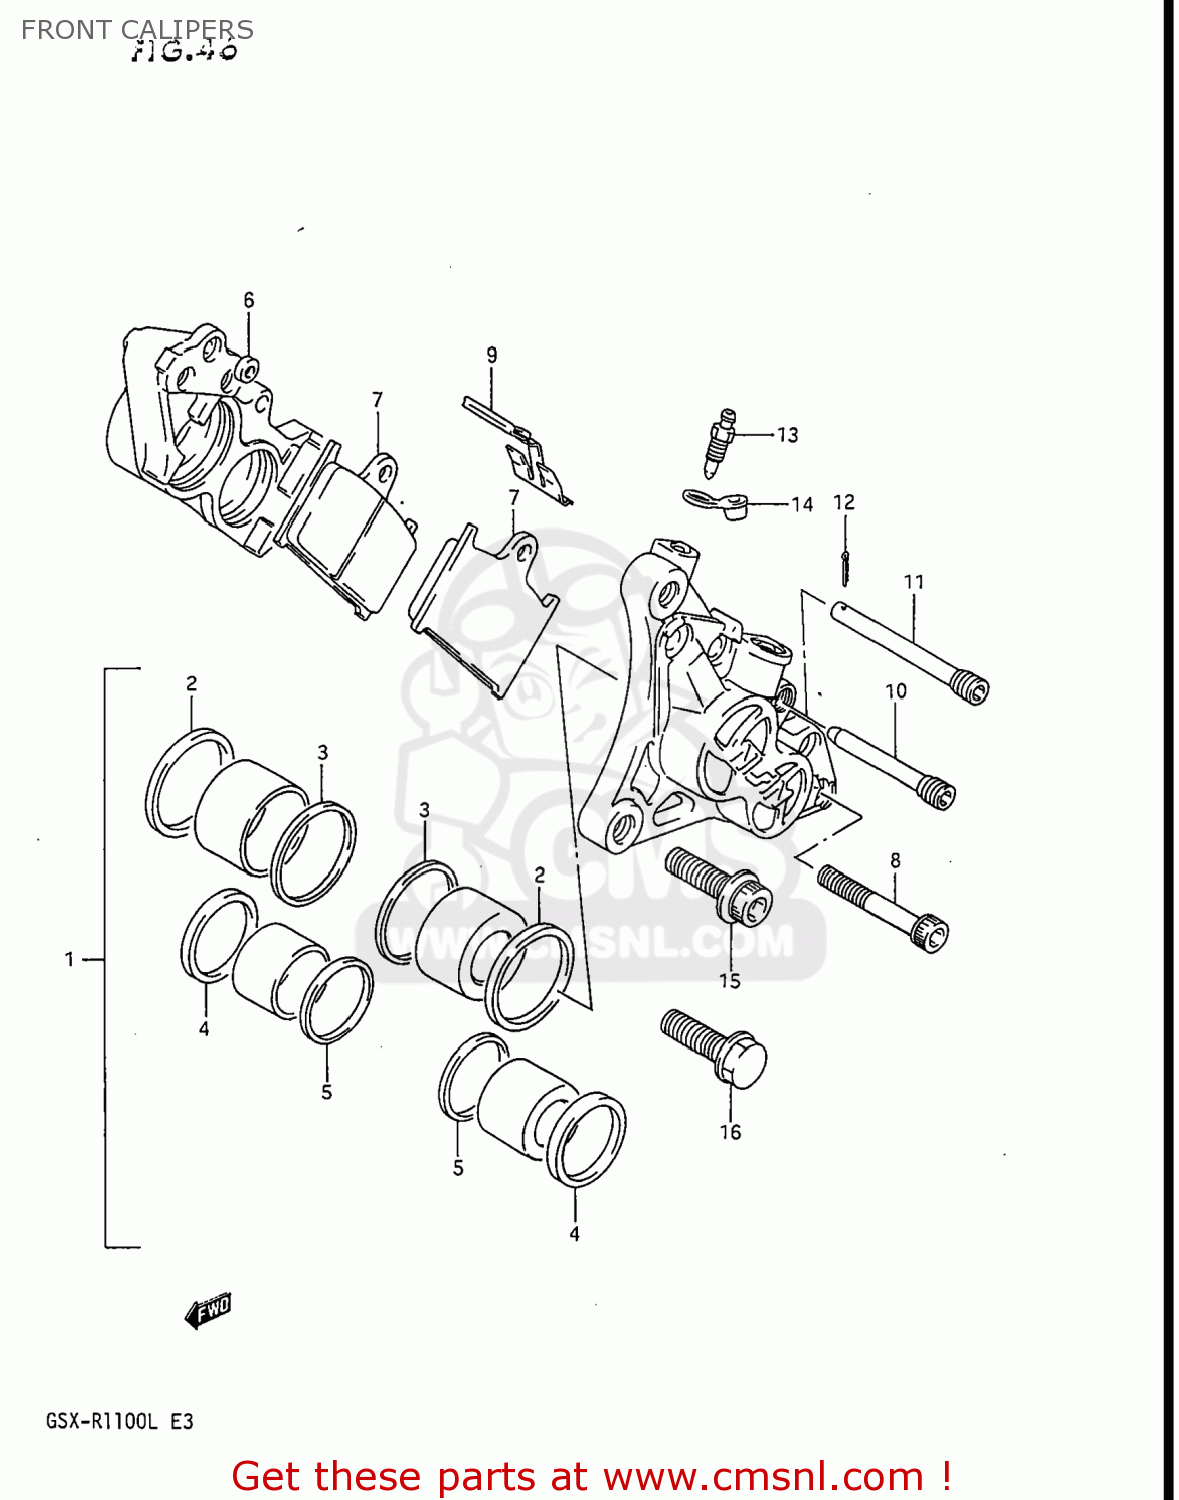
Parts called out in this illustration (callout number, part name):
1	PISTON SET
2	SEAL,PISTON
3	BOOT,PISTON
4	SEAL,PISTON
5	SEAL
6	SEAL
7	PAD
8	BOLT
9	SPRING
10	PIN,HOLDER
11	PIN,HANGER
12	COTTER PIN
13	BLEEDER
14	CAP,BLEEDER
15	BOLT
16	BOLT 10X30
